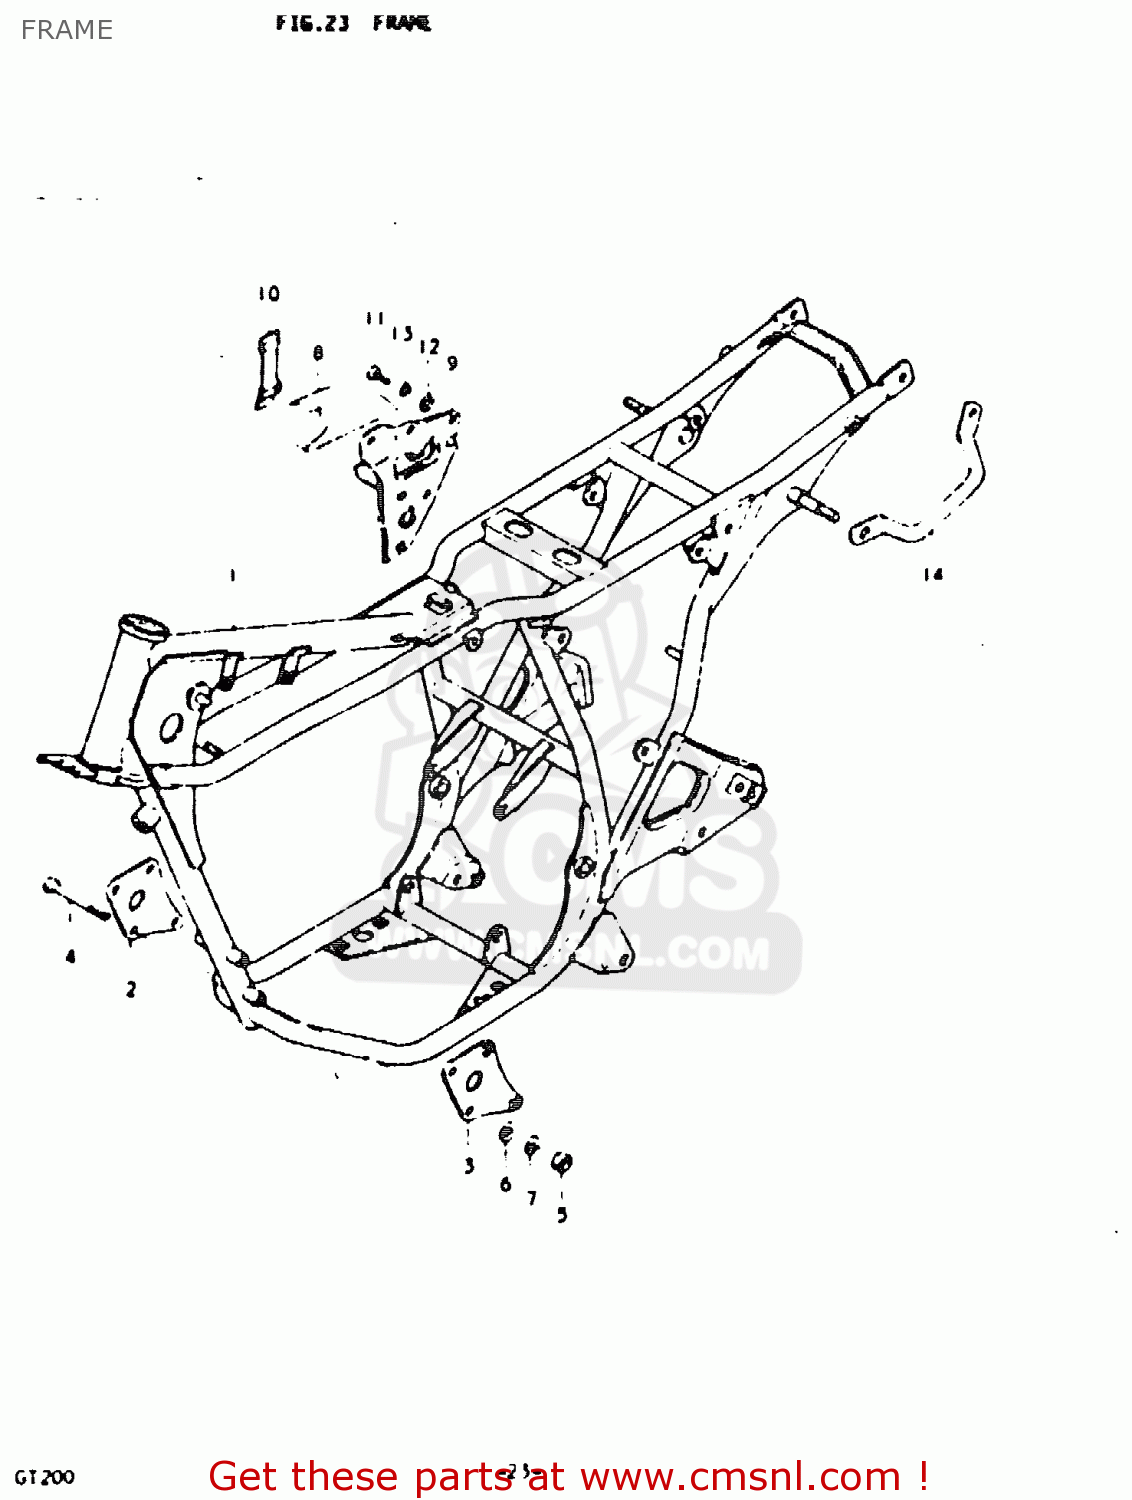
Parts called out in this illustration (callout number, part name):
1	FRAME
2	PLATE, ENGINE MOUNTING RH
3	PLATE, ENGINE MOUNTING LH
4	BOLT,8X75
5	NUT
6	WASHER
7	LOCK WASHER
8	TOOL SET
9	HOLDER, TOOL
10	BAND
11	BOLT
12	WASHER(6.5X16X1.2)
13	LOCK WASHER
14	GRIP, FRAME HANDLE
